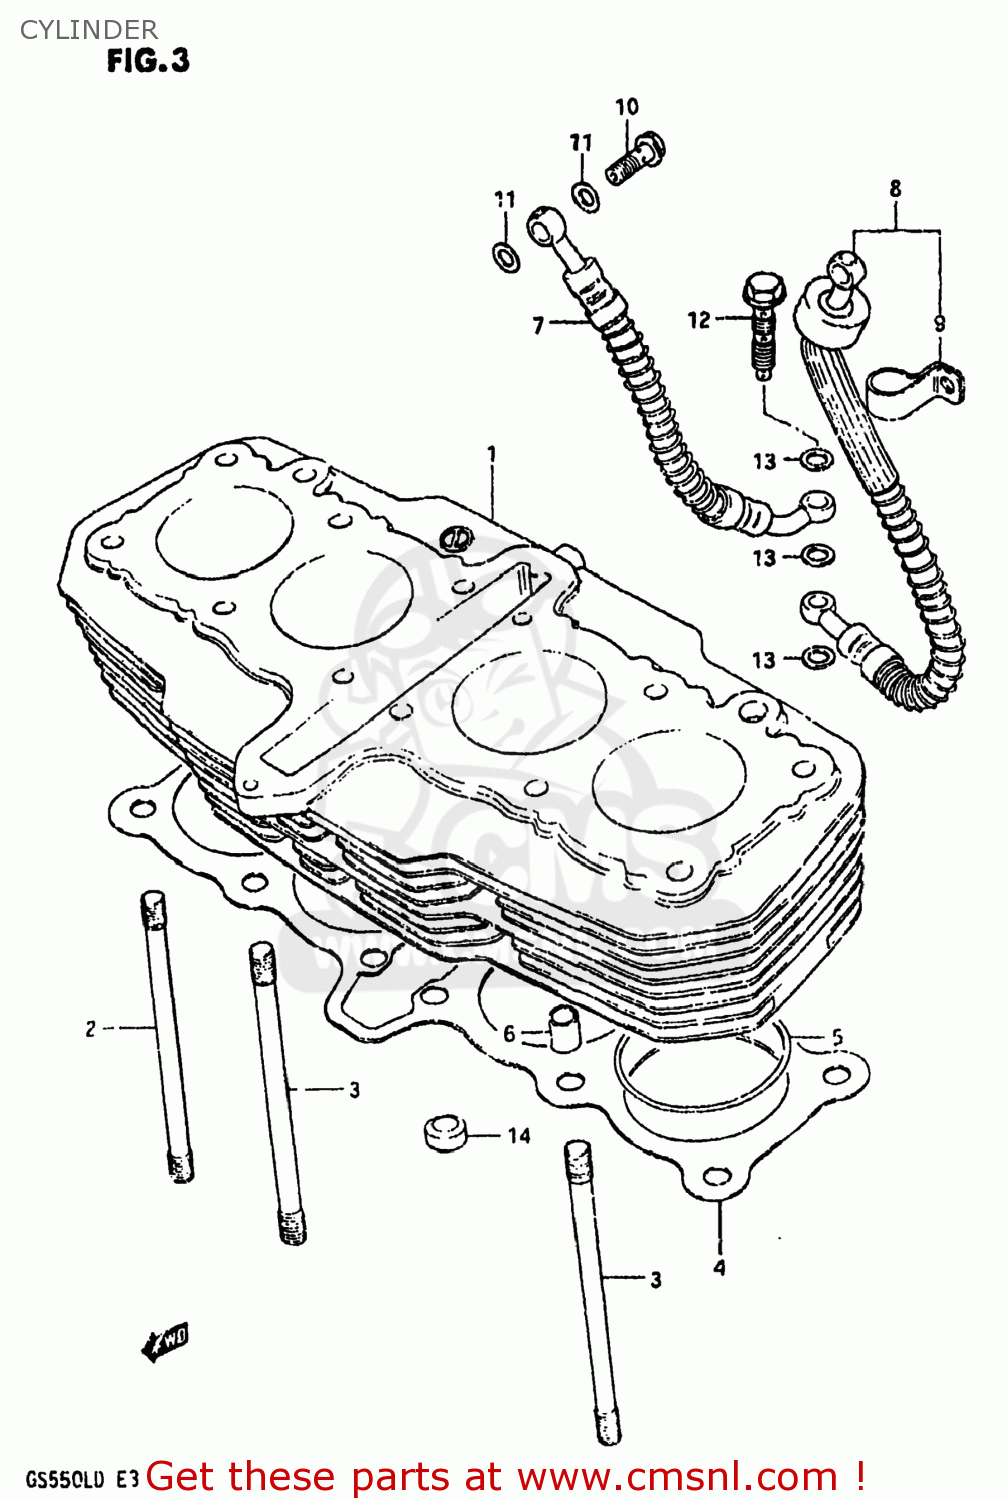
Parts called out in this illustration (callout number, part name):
1	CYLINDER
2	STUD
3	STUD
4	GASKET,CYLINDER (MCA)
5	O RING(D:2,ID:61)
6	PIN
7	HOSE,OIL CRANKCASE,R
8	HOSE,OIL
9	CLAMP,OIL HOSE CRANKCASE
10	BOLT UNION
11	GASKET 8.2X14X1 (NAS)
12	BOLT,OIL PIPE
13	WASHER
14	PAD,CYLINDER HEAD
